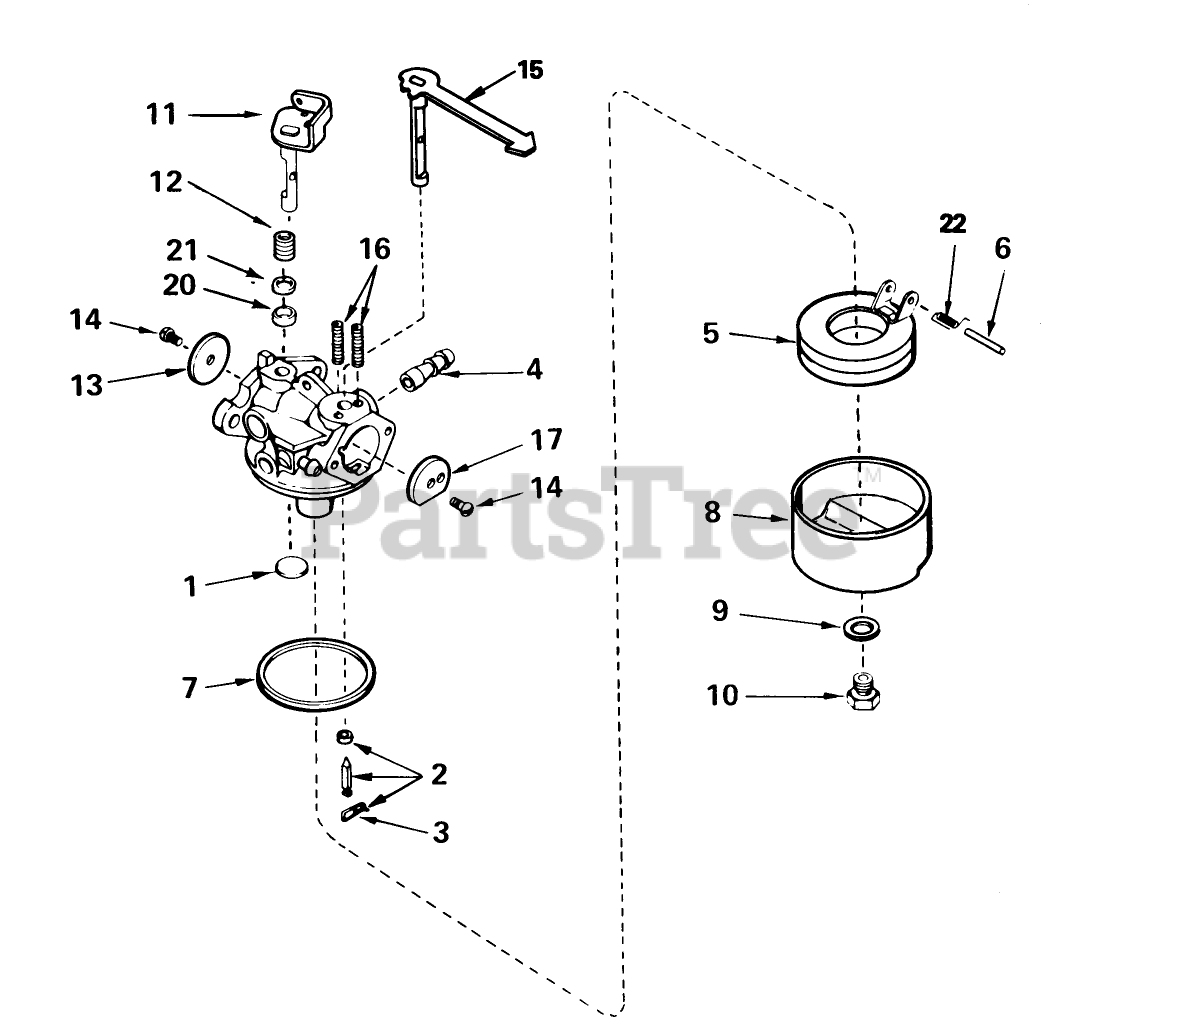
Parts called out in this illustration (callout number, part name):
1	Plug-Welch, Atmospheric Vent
2	Inlet Needle, Seat Clip Assy. (Incl. No. 13)
3	Clip-Spring
4	Fitting-Fuel
5	Float
6	Shaft-Float
7	O Ring-Bowl, Float
8	Bowl Float
9	Gasket-Bowl
10	Nut-Float Bowl
11	Shaft/Lever-Throttle
12	Spring-Trottle, Return
13	Shutter-Throttle
14	Screw-Shutter
15	Choke Shaft Lever Assy.
16	Spring-Positioning, Choke
17	Shutter-choke
20	Seal-Dust
21	Washer-Seal, Dust
22	Spring-Float, Dampening
